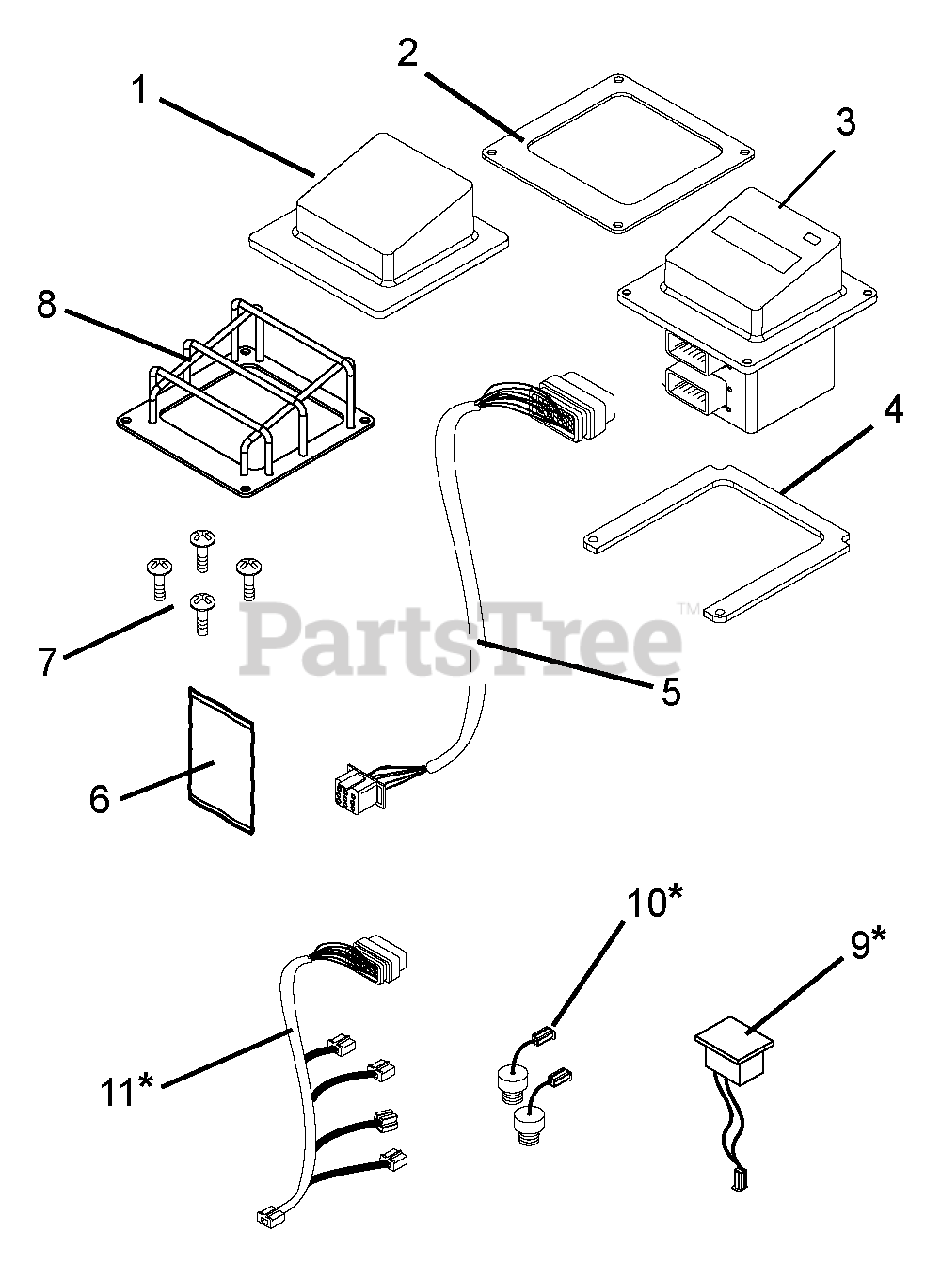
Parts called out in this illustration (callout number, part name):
1	Element Guard
2	Eye-Q™ Gasket
3	Eye-Q™ 2006
4	Mounting Enclosure Spacer
5	Eye-Q™ Harness
6	Eye-Q™ Owner/Operator Manual
6	Eye-Q™ Owner/Operator Manual - Multilingual
7	10-24 x 1 Slotted Panhead Machine Screw (Black)
8	Eye-Q™ Guard
9	Eye-Q™ Accelerometer Kit
10	Eye-Q™ Temperature Kit
11	Eye-Q™ Accessory Wire Harness
